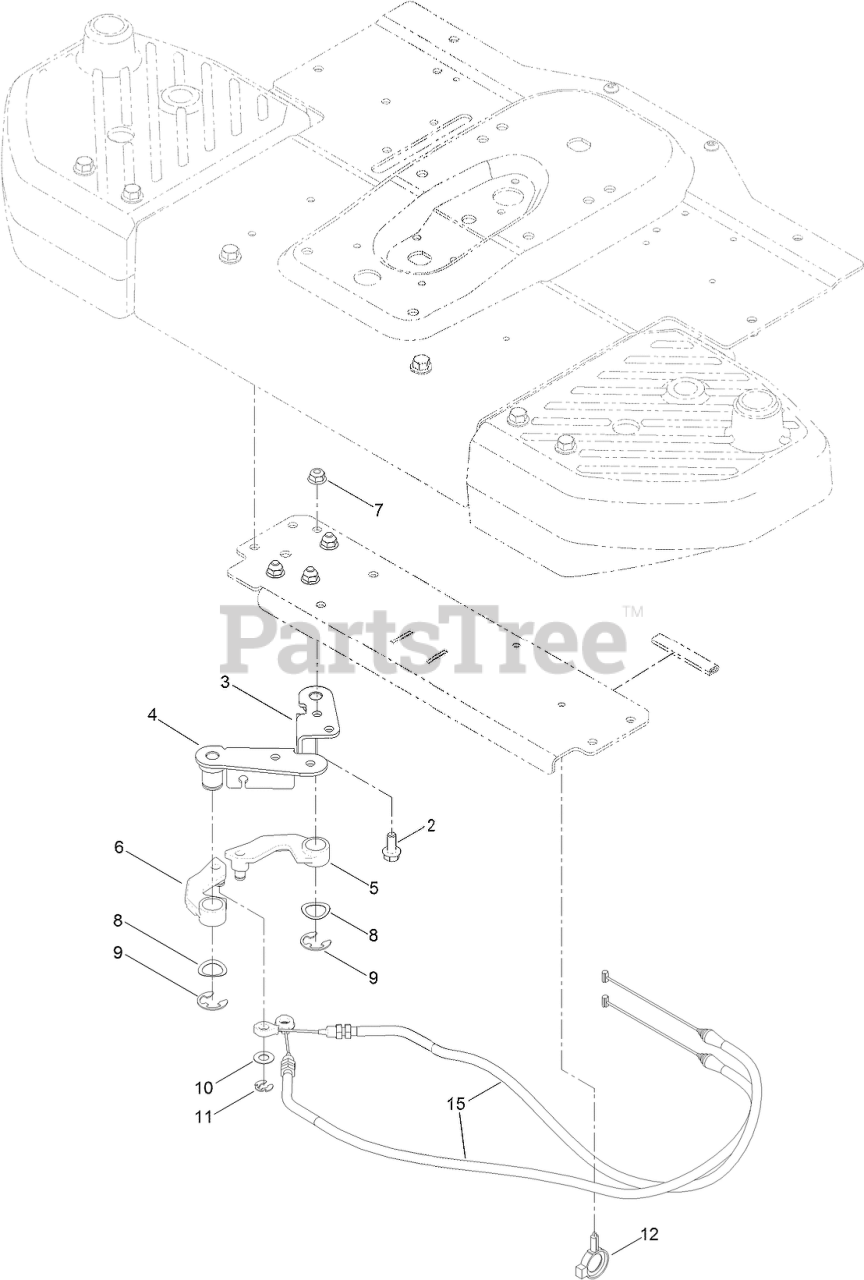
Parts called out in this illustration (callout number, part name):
2	SCREW-HHF
3	CABLE BRACKET ASM
4	CABLE BRACKET ASM
5	ARM-CABLE, RH
6	ARM-CABLE, LH
7	NUT-HF, NI
8	WASHER-BOWED
9	E-RING
10	WASHER-THRUST
11	RING-RETAINING
12	CLAMP-HOSE
15	CABLE-STEERING
